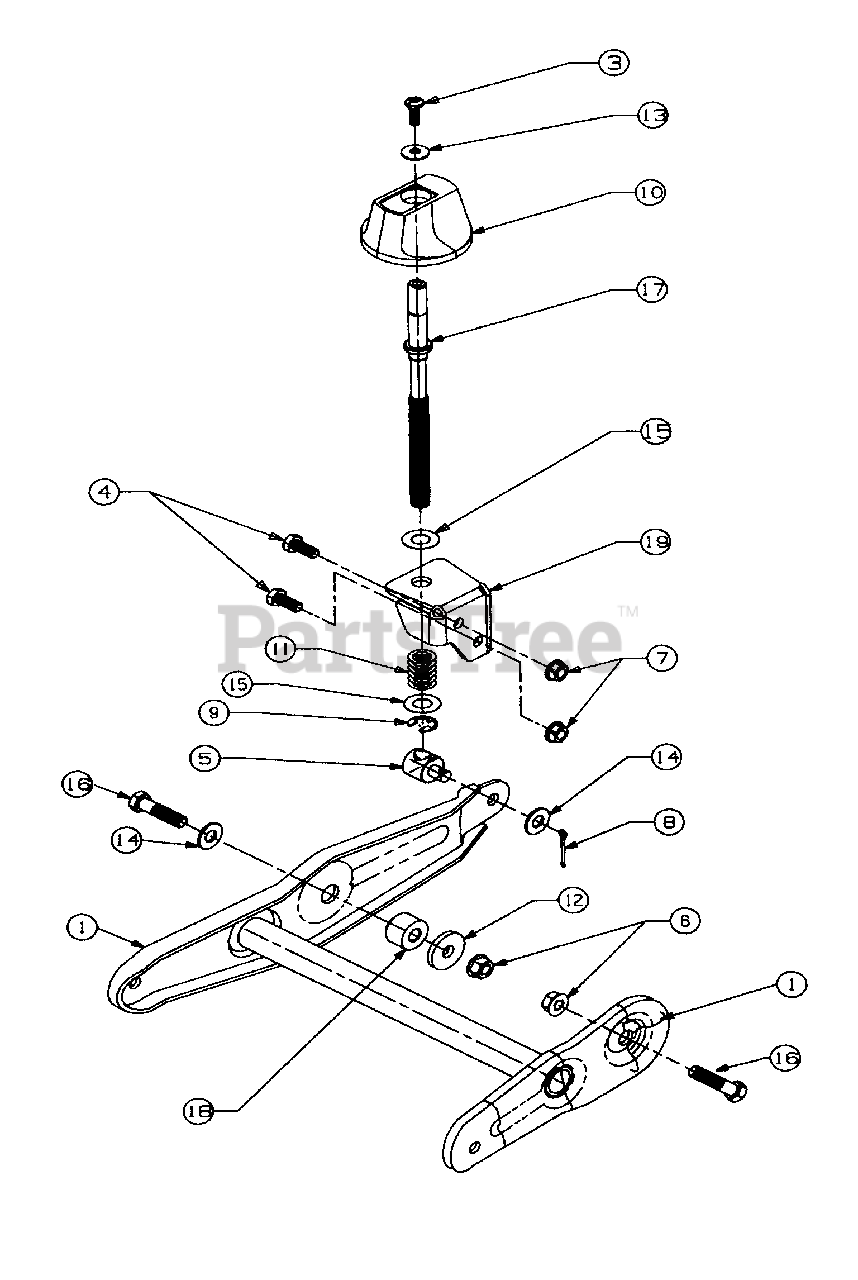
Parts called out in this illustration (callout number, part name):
4	SCREW-HEX
5	FERRULE--ADJUSTABLE
6	NUT-HEX FLANGE LOCK
7	NUT-HEX FLANGE
8	PIN-COTTER
9	RING-E
10	KNOB-PLASTIC
11	SPRING-COMPRESSION
12	WASHER-FLAT
13	WASHER-BELL
14	WASHER-FLAT
15	WASHER-FLAT
16	SCREW-SHOULDER
17	ROD-ADJUSTABLE
18	SPACER
